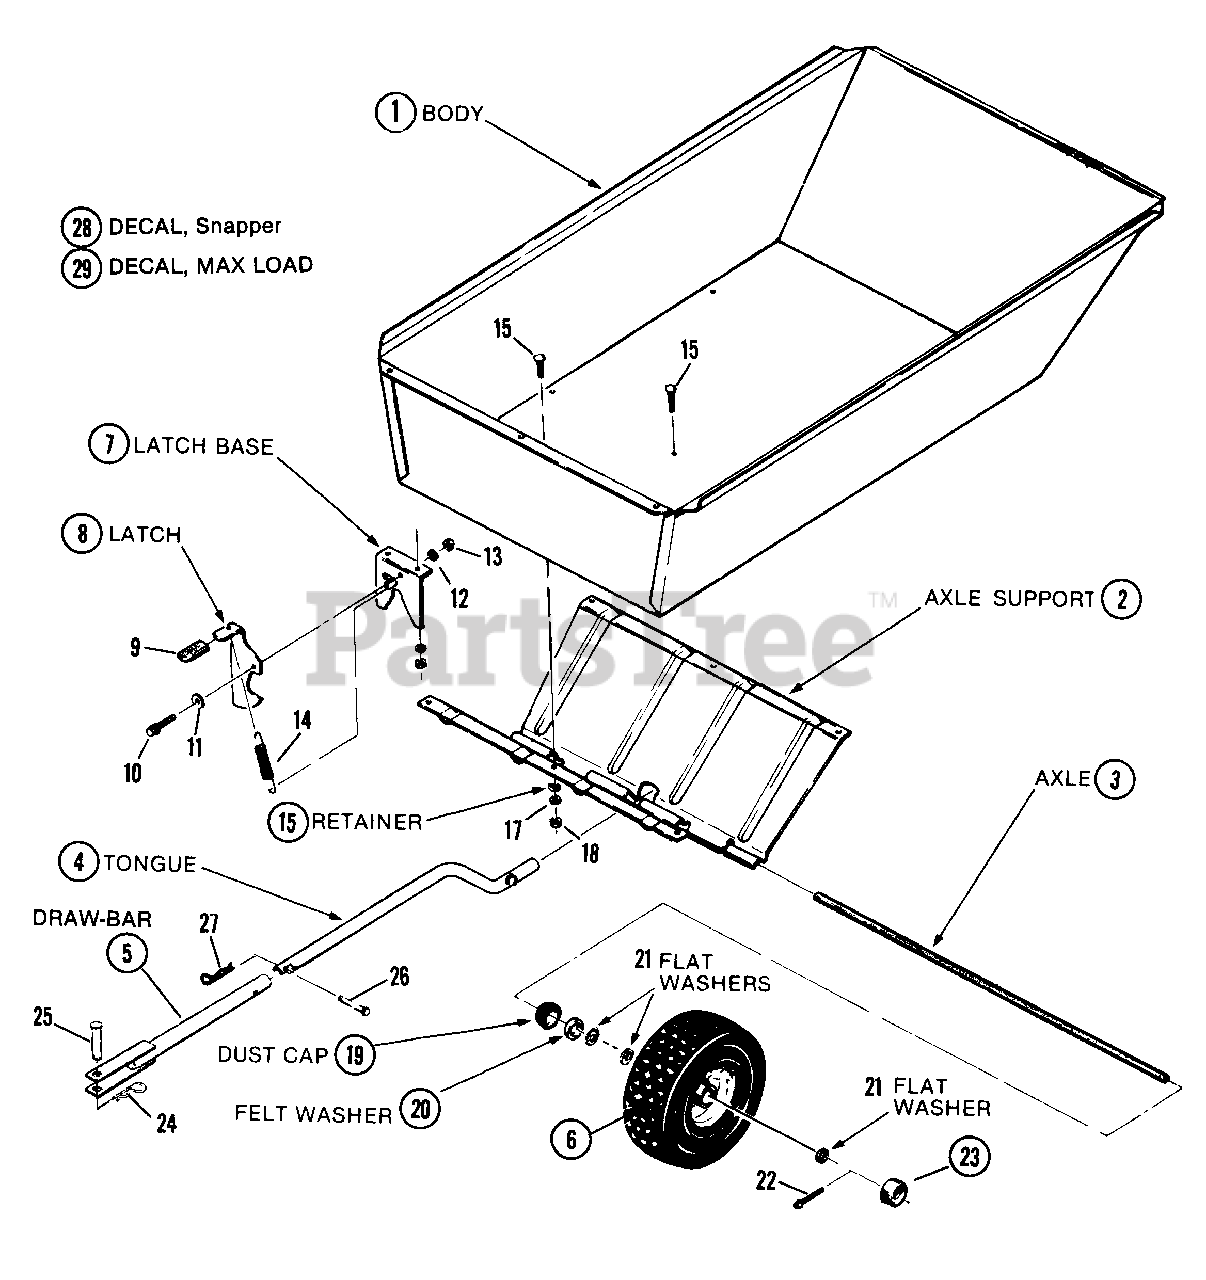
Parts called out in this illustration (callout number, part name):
1	BODY, Dump Wagon
2	SUPPORT, Axle
3	AXLE
4	TONGUE
5	DRAW-BAR
6	TIRE, Semi-Pneumatic
7	BASE, Latch (Yoke)
9	GRIP, Latch
10	BOLT, 5/16-18 Shoulder
11	WASHER, Spring
12	LOCKWASHER, 5/16 Split
13	NUT, 5/16-18 Hex
14	SPRING, Latch
15	BOLT, 1/4-20 x 3/4 Carriage
17	LOCKWASHER, 1/4 Intern
18	NUT, 1/4-20 Hex
19	DUST CAP
20	WASHER, Felt
21	WASHER, Flat
22	COTTER-PIN, 5/32 x 1"
23	HUB-CAP
24	CLEVIS-PIN, 1/2-2
25	HAIR-PIN, 1-7/16
26	CLEVIS-PIN, 3/8 x 2-1/4
27	HAIR-PIN, 3/32 x 1-7/8
28	DECAL, Snapper
29	DECAL, MAX LOAD Warn
